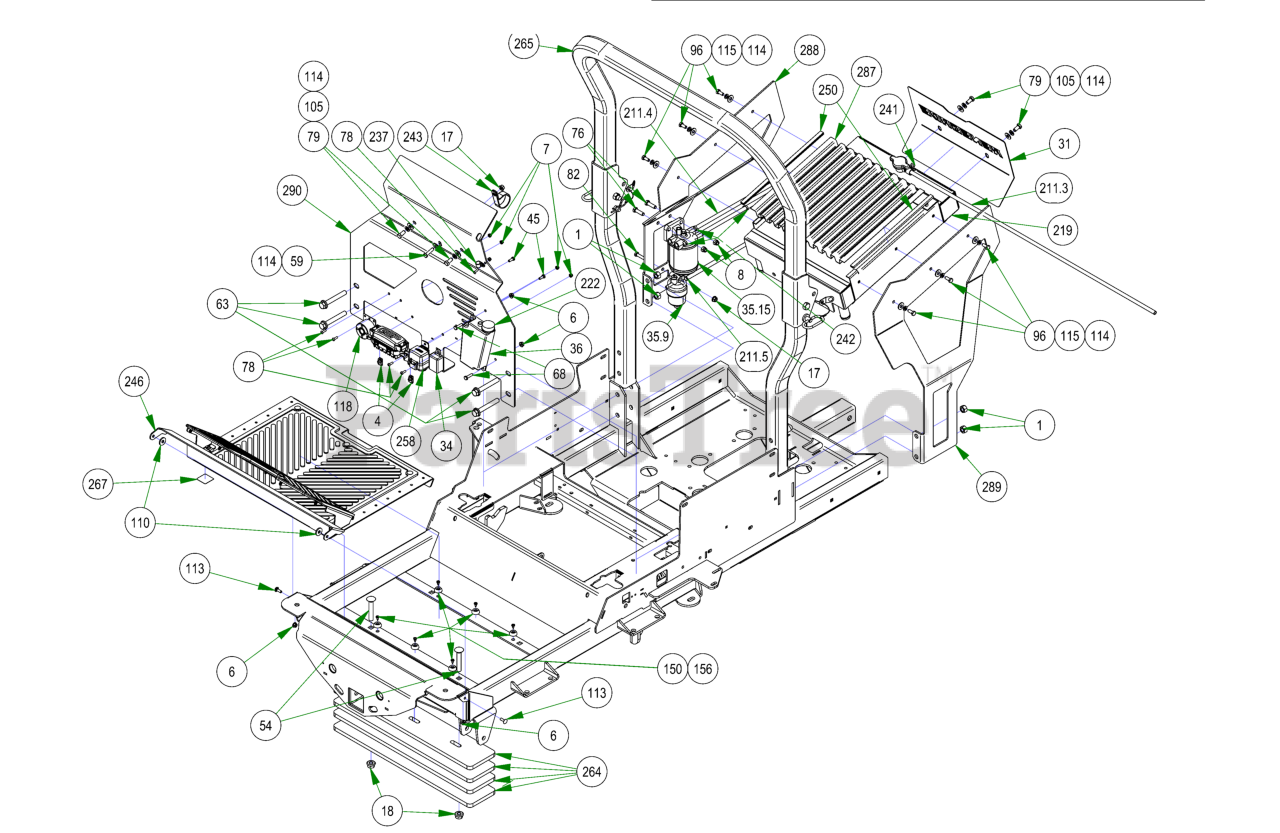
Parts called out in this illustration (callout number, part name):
1	1/2-13 HEX 2-WAY REVERSIBLE CENTER LOCKNUT Grade B ZINC
4	1/4-20 Cage Nut
6	1/4-20 NYL INSERT FLANGE LOCKNUT ZINC
7	10-24 NYLON INSERT LOCKNUT ZINC
8	3/8-16 NYLON INSERT LOCKNUT ZINC
17	5/16-18 NYLON INSERT FLANGE LOCKNUT ZINC
18	1/2-13 NYLON INSERT FLANGE LOCKNUT ZINC
31	2019 Diesel Upper Rear Cover - Black
34	Auto Shut Down for Cat Diesels
35.9	FUEL PRE-FILTER
35.15	Fuel Filter
36	overflow Reservoir- 27Kaw & 28/35Hp Diesel
45	M6-1.0 X 16MM DIN 933 HEX TAP BOLT (CL 8.8) ZINC
54	1/2-13 x 3 Carriage Bolt Grade 5
59	5/16-18 X 1-1/4 HEX C/S (GR.5) ZC
63	1/2-13 X 3-1/2 HEX FLANGE BOLT (GR.8) ZINC
68	1/4-20 X 1 HEX CAP SCREW (GR.5) ZINC
76	3/8-16 X 1-1/4 HEX CAP SCREW (GR.5) ZINC
78	10-24 X 5/8 BUTTON SOCKET CAP SCREW 18-8 STAINLESS STEEL
79	3/8-16 X 3/4 HEX CAP SCREW (GR.5) ZINC
82	5/16-18 X 2-1/2 HEX CAP SCREW (GR.5) ZINC
96	5/16-18 X 3/4 HEX CAP SCREW (GR.5) ZINC
105	3/8 SPLIT LOCKWASHER ZINC
110	.360 ID X .983 OD X .120 THICK FLAT WASHER NYLON
113	1/4-20 X 3/4 CARRIAGE BOLT (GR.5) ZINC
114	5/16 USS FLAT WASHER (7/8 OD) ZINC
115	5/16 SPLIT LOCKWASHER ZINC
118	Heat Warning Piezo Buzzer
150	Button Bumper
156	10-16 X 1/2 PAN PHIL TEK/3 CLIMASEAL OR ACF-SILVER COATED
211	2022 Renegade Diesel Fuel Line Assembly
211.3	5/16 Clear Hose
211.4	5/16" fuel line hose
211.5	5/16 Fuel Line Clamp
219	2019 Diesel Radiator Kit
222	Reservoir Tank Cap-Overflow
235	2022 Horizontal Diesel Frame
237	3/8 Cable Clamp-Black Nylon
241	5/8 Hose Clamp
242	2 EAR CLAMP 12.5mm-15mm
243	Diesel Clamp 1 3/4" Vinyl
246	R-Series Floorboard Assembly
250	Rubber Trim
258	2022 Renegade Diesel Wiring Harness
264	2019 Outlaw Counter Weight
265	2019 2X2 Folding ROPS
267	Patent Decal (Anti-Wobble)
287	Radiator Screen Diesel
288	2019 Diesel Radiator Mount - Right
289	2019 Diesel Radiator Mount - Left
290	2022 Diesel Radiator Mount
